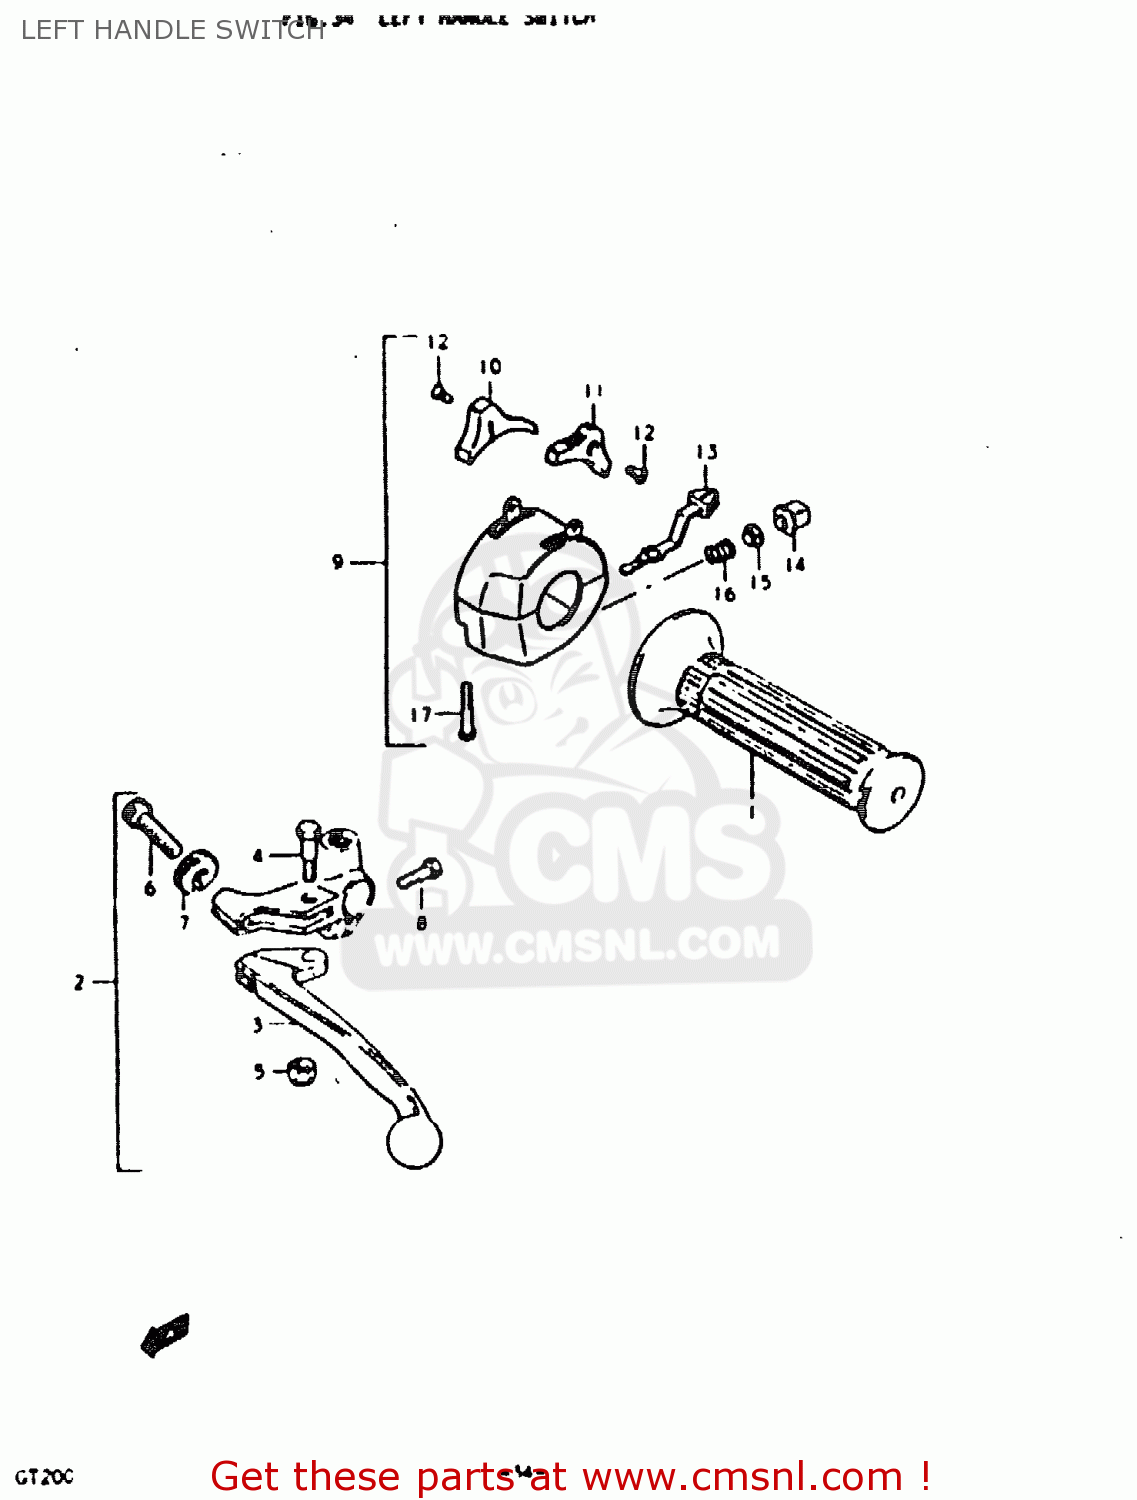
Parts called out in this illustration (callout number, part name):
1	GRIP,L
2	LEVER ASSY,CLUTCH
3	LEVER,CLUTCH
4	BOLT,LEVER
5	NUT 6MM
6	ADJUSTER,CABLE
7	NUT,CABLE ADJUSTER
8	BOLT
9	SWITCH ASSY, HANDLE LH
10	KNOB,LIGHTING SWITCH
11	KNOB,DIMMER SWITCH
12	SCREW
13	KNOB,TURNSIGNAL
14	BUTTON,HORN
15	CONTACT
16	SPRING
17	SCREW
